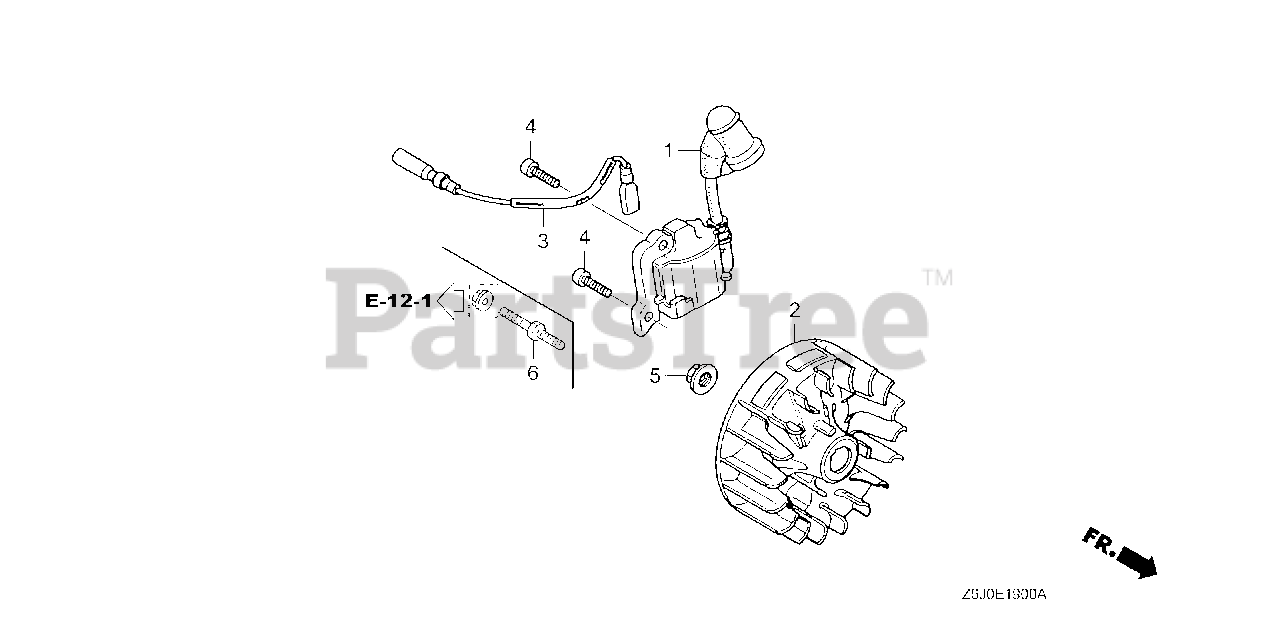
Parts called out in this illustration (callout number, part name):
1	COIL ASSY., IGNITION
2	FLYWHEEL
3	WIRE, STOP SWITCH
4	BOLT, SOCKET (4X14)
5	NUT, FLANGE (7MM)
